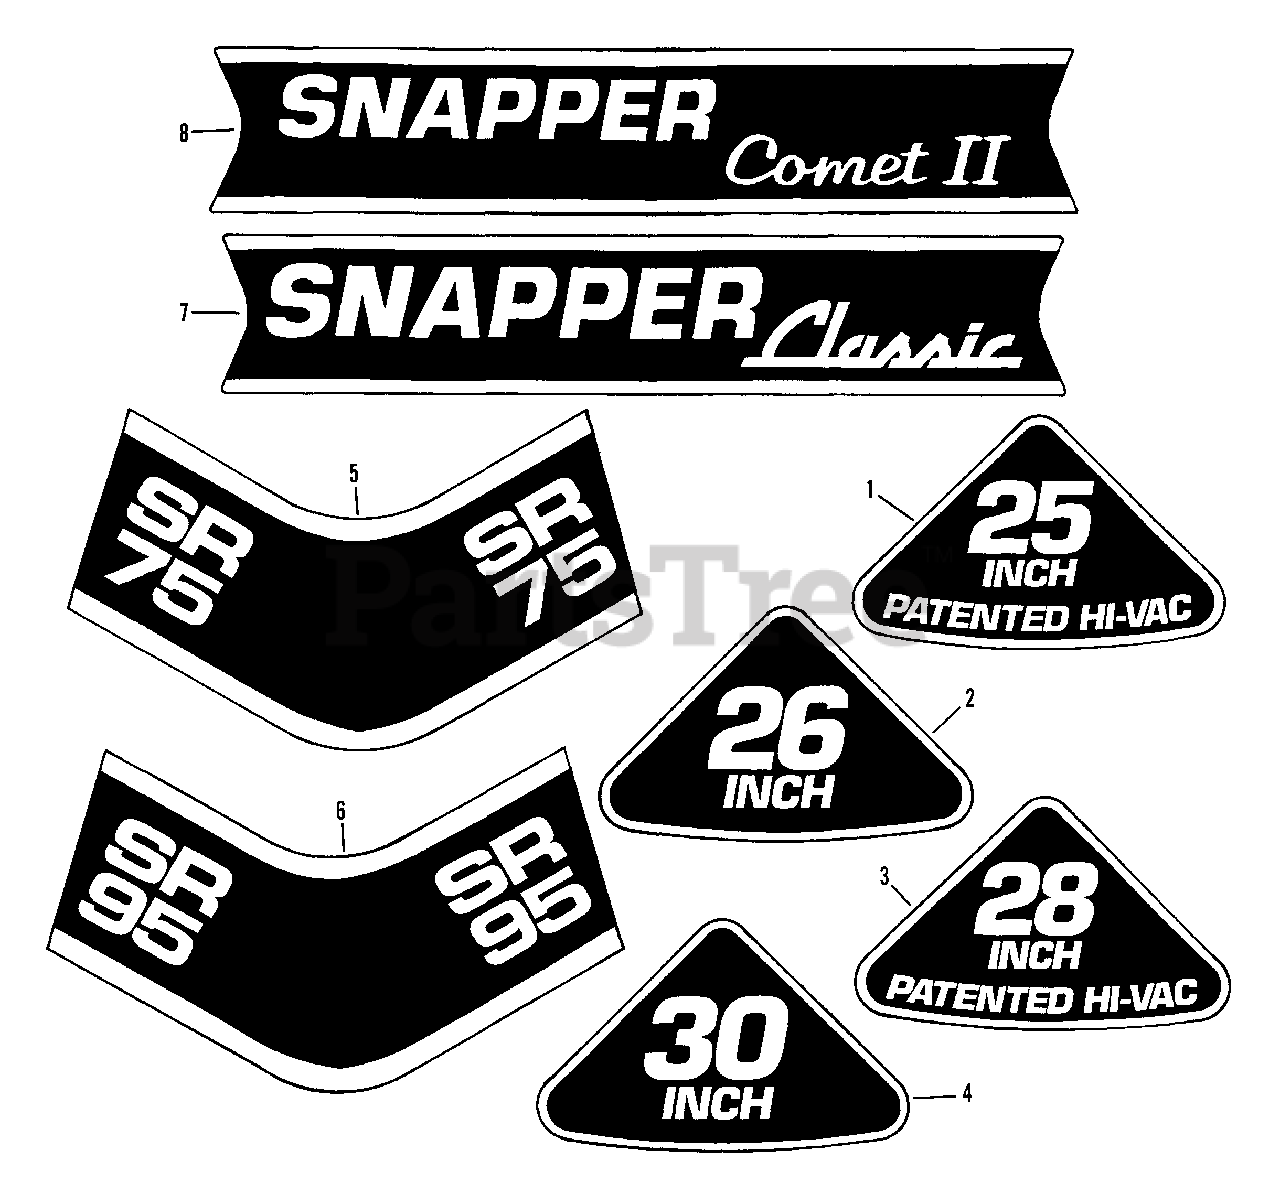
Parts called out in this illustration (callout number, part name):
1	DECAL, 25 Inch
2	DECAL, 26 Inch
3	DECAL, 28 Inch
4	DECAL, 30 Inch
5	DECAL, SR75
6	DECAL, SR95
7	DECAL, SNAPPER Classic
8	DECAL, SNAPPER Comet II
